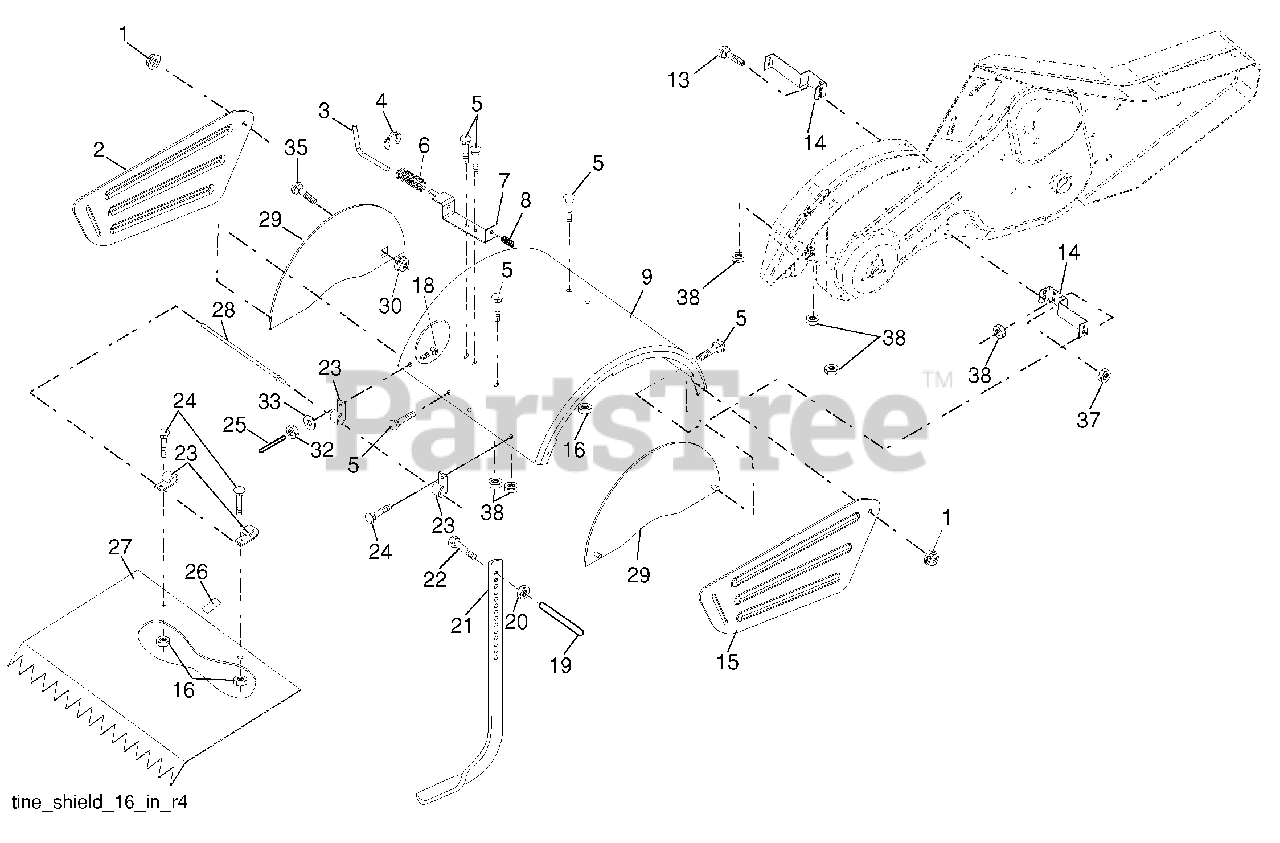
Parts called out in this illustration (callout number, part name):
1	Nut, Lock Hex Flange 5/16-18
2	Shield, Side, Outer L. H.
3	Pin, Stake, Depth
4	Ring, Klip
5	Bolt 5/16-18 x 3/4 ZNC
6	Spring
7	Bracket, Latch
8	Spring, Depth Stake
9	Shield, Tine
13	Bolt, Carriage 5/16-18 x 1-1/4
14	Bracket, Shield Tine
15	Shield, Side, Outer R.H.
16	Nut, Hex Flange 1/4-20 unc
18	Bolt, Carriage 1/4-20 x 1-1/4 Gr. 5
19	Grip
20	Nut, Hex 3/8-16
21	Stake, Depth
22	Bolt, Hex 3/8-16 x 2
23	Hinge
24	Bolt, Carriage 1/4-20 x 1/2 Gr. 5
25	Cap, Vinyl
26	Pad, Idler
27	Shield, Leveling
28	Pin, Hinge
29	Shield, Side
30	Locknut, Flange 5/16-18
32	Nut Fin Hex 1/4-20 unc
33	Washer Lock Hvy Helical 1/4
35	Bolt, Carriage 5/16-18 x 5/8
37	Nut, Lock Hex 5/16-18 unc
38	Nut, Keps 5/16-18 unc
